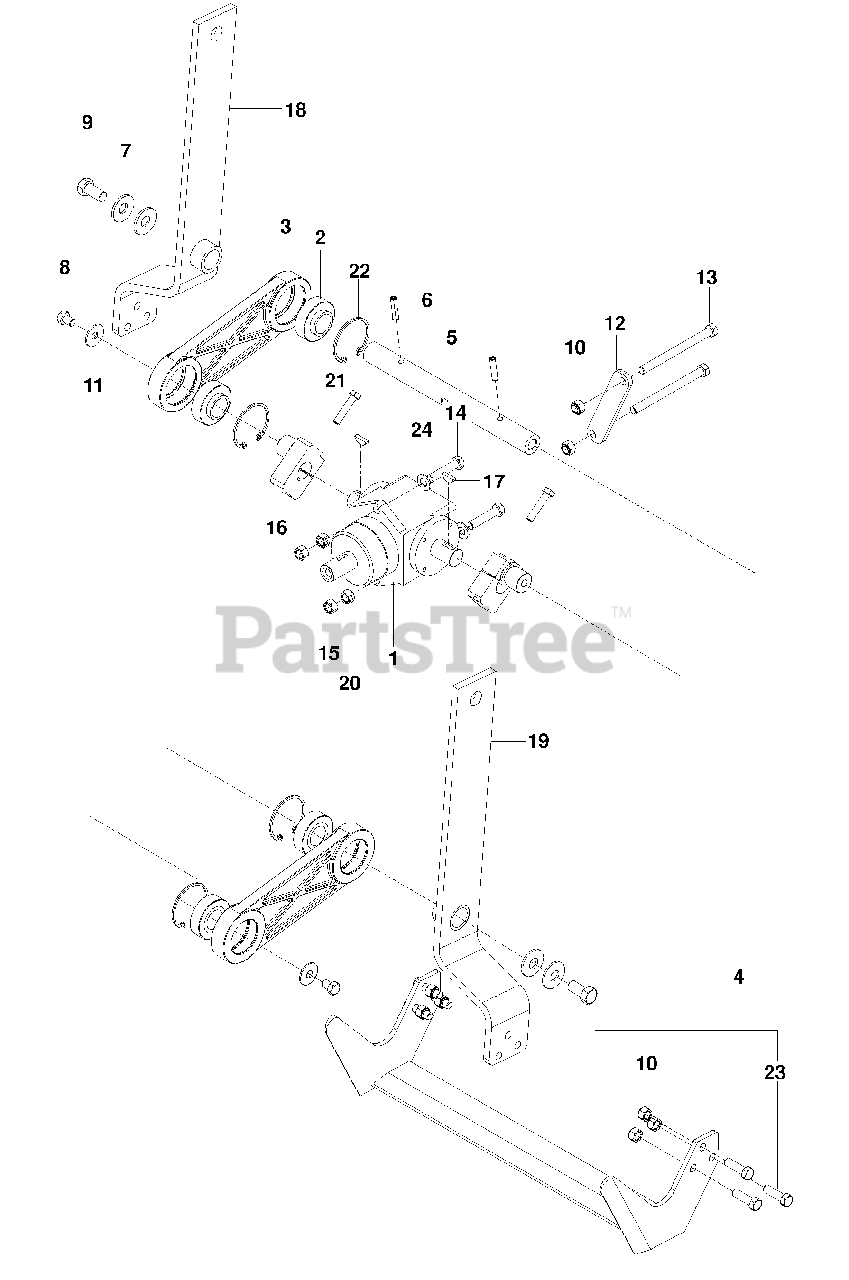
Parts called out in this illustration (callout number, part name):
1	GEAR BOX
2	BEARING
3	LINK, CONNECTING
4	BLADE KIT, 18"
5	SHAFT, BLADE ARM
6	SPIRAL PIN 1/4 x 1 1/4
7	SPRING WASHER 1/2
8	HCS 3/8-16 x 1/2
9	HCS 1/2-13 x 1
10	NUT 3/8-16 NYLOC
11	SPRING WASHER 3/8
12	STRAP, T BOX
13	HCS 3/8-16 x 4 1/2
14	HCS 3/8-24 x 1 3/4 GR 8
15	NUT 3/8-24 GR2
17	KEY, WOODRUFF #9
18	BLADE ARM, RH
19	BLADE ARM, LH
20	NUT 3/8-24 CTR LK
21	HCS 5/16-18 x 1 1/2
22	SNAP RING 52mm
23	HCS 3/8-16 x 1 1/4 GR 8
24	WASHER 3/8 SAE
